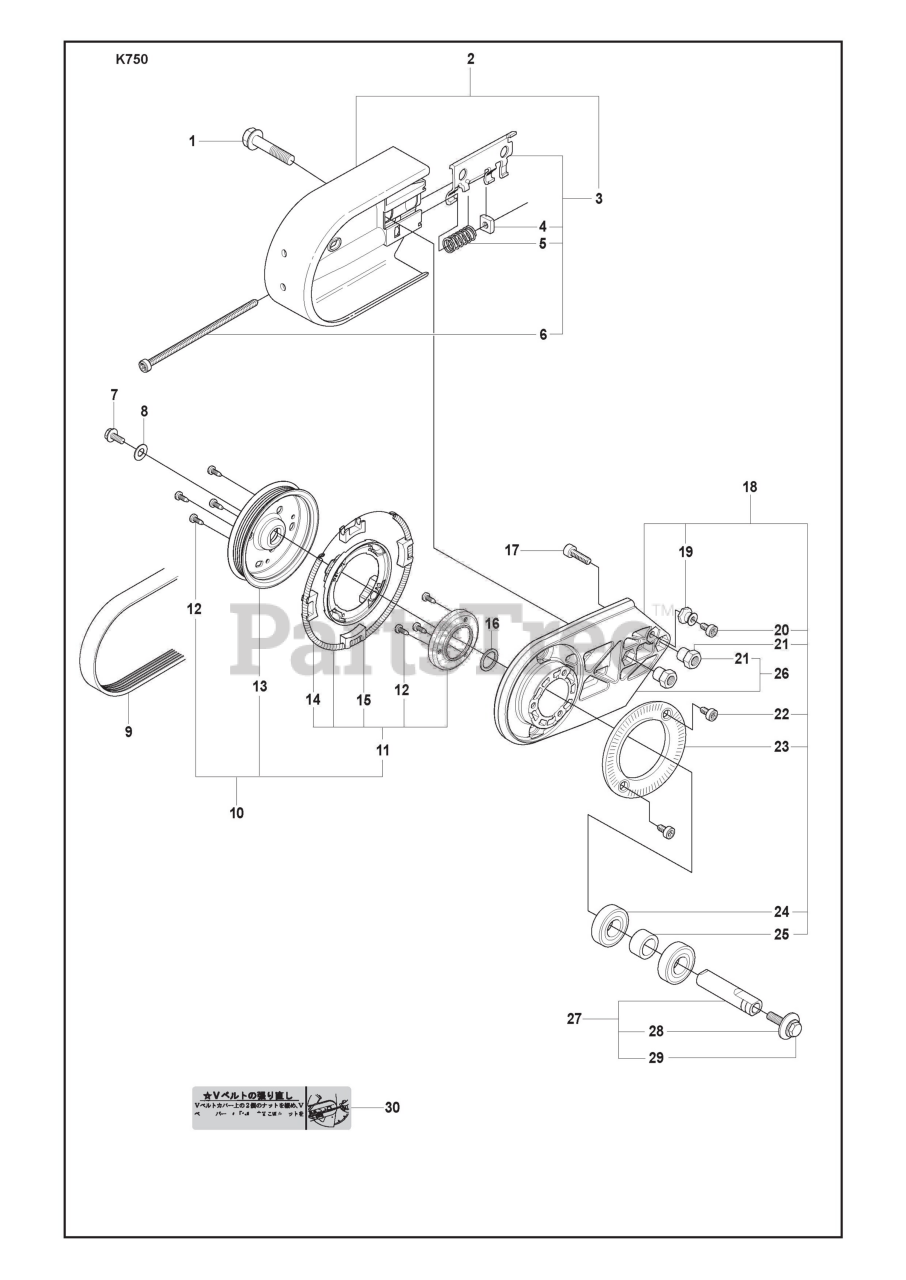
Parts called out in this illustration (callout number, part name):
1	COLLAR SCREW
2	BELT GUARD
3	BELT TENSIONER ASSY
5	COMPRESSION SPRING
8	WASHER STEEL
10	PULLEY WITH RETARDER
11	RETARDER CPL
15	BRAKE SHOE
16	WASHER STEEL
18	BEARING HOUSING
19	TORSION STOP
23	RATCHET FLANGE
24	BALL BEARING
25	SPACING SLEEVE
26	BEARING HOUSING
27	SHAFT
28	WASHER
29	COLLAR SCREW
30	LABEL
